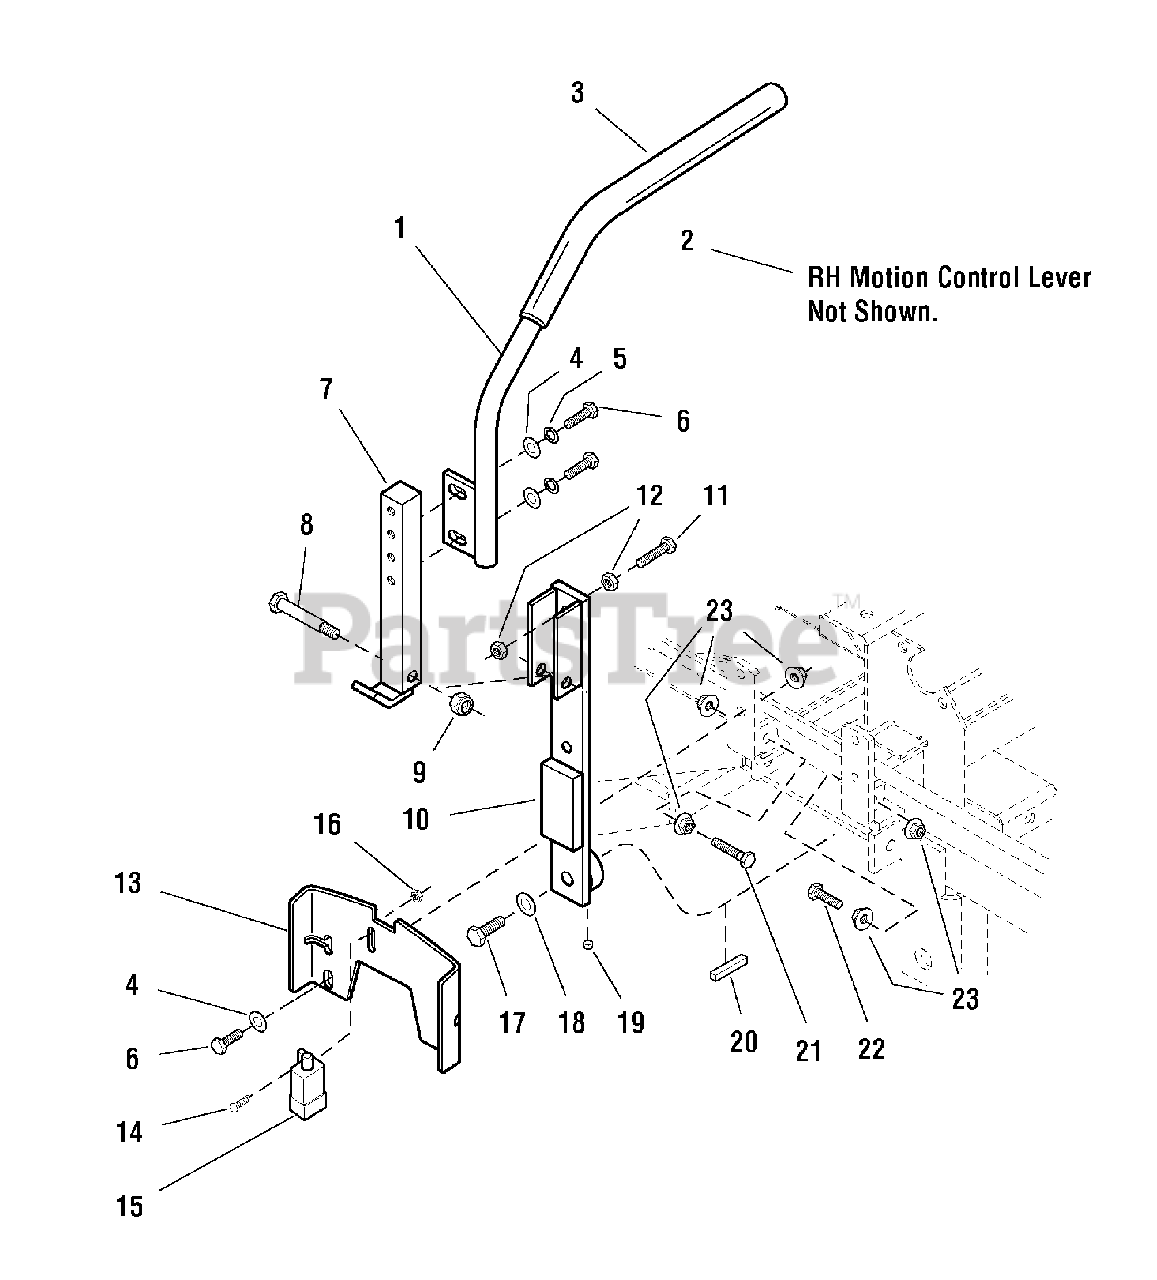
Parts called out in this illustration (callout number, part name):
1	MOTION CONTROL LEVER-RH
2	MOTION CONTROL LEVER-LH
4	WASHER, 5/16" SAE
5	WASHER, 5/16" Lock
6	BOLT, 5/16-18 x 3/4
7	CONTROL LEVER BASE
8	BOLT, 3/8-16 x 2
9	NUT, 3/8-16 Hex Nylon Lock
10	CONTROL LEVER MOUNT
11	BOLT, 5/16-18 x 1
12	NUT, 5/16-18 Hex
13	NEUTRAL LOCK PLATE
14	SCREW, #10-24 x 1
15	SWITCH
16	NUT, #10-24 Hex
17	BOLT, 3/8-16 x 1-1/4 w/ patch
18	WASHER, 3/8" SAE
19	SET SCREW, 5/16-18 x 1/4 w/ patch
20	KEY, 1/4 SQ. X 1
21	BOLT, 5/16-18 x 1-3/4
22	BOLT, 5/16-18 x 1-1/4
23	NUT, 5/16-18 Hex Small Serrated Flange
